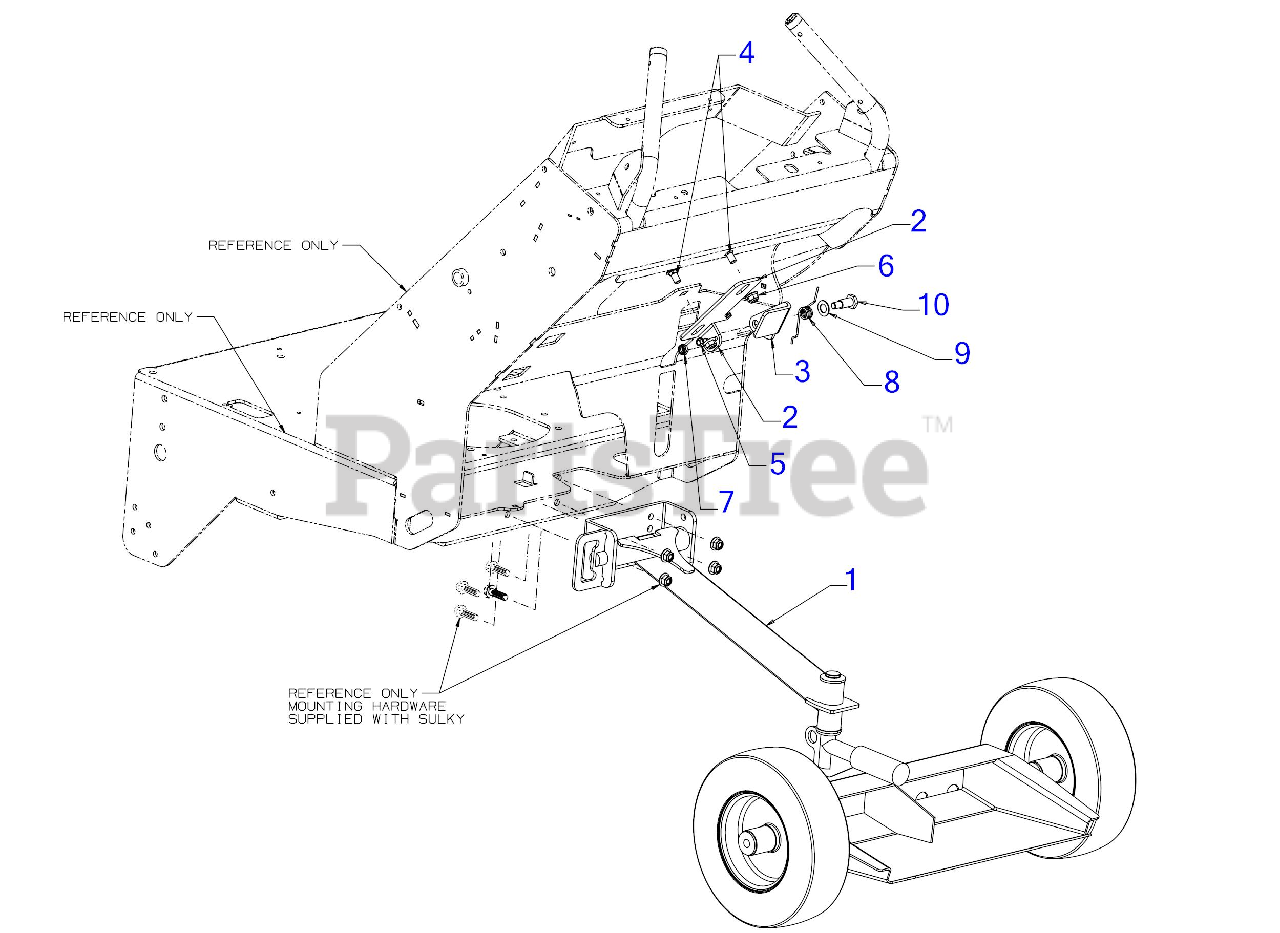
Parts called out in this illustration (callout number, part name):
1	NOT SERVICEABLE
4	CARRIAGE BOLT 3/8-16 x .750 GR5
5	SCREW 1/4-20 X.500
7	TOP LOCK NUT
8	TORSION SPRING
9	FLAT WASHER
10	SHOULDER SCREW .500
